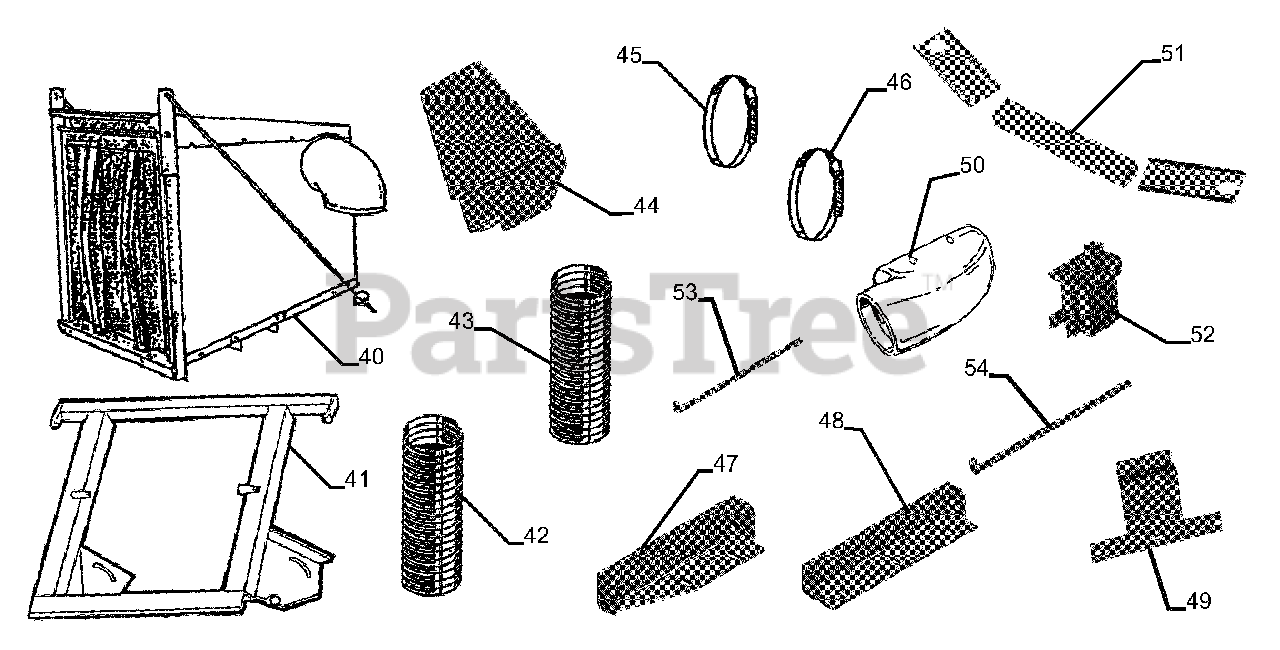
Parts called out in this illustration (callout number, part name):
40	12 cu. ft. Box Assembly
41	Top Main Frame Assembly
42	8" x 36" Lower Hose
43	6" x 36" Upper Hose
44	Left Main Frame Leg Assembly
45	7" - 8" Hose Clamp
46	5" - 6" Hose Clamp
47	52" Deck Boot Plate -Boot Plate Changed After Serial# 351
48	60" Deck Boot Plate -Boot Plate Changed After Serial# 351
49	Boot Hanger
50	52" Deck Boot
50	60" Deck Boot
51	Weight Kit
51	100lb. Weight Bar
51	Weight Bracket
51	A33K Kevlar Cord Blower Belt
51	A56K Kevlar Cord PTO Belt
52	Interlock Switch
53	52" Deck Boot Rod -Added Boot Rod After Serial# 351
54	60" Deck Boot Rod -Added Boot Rod After Serial# 351
